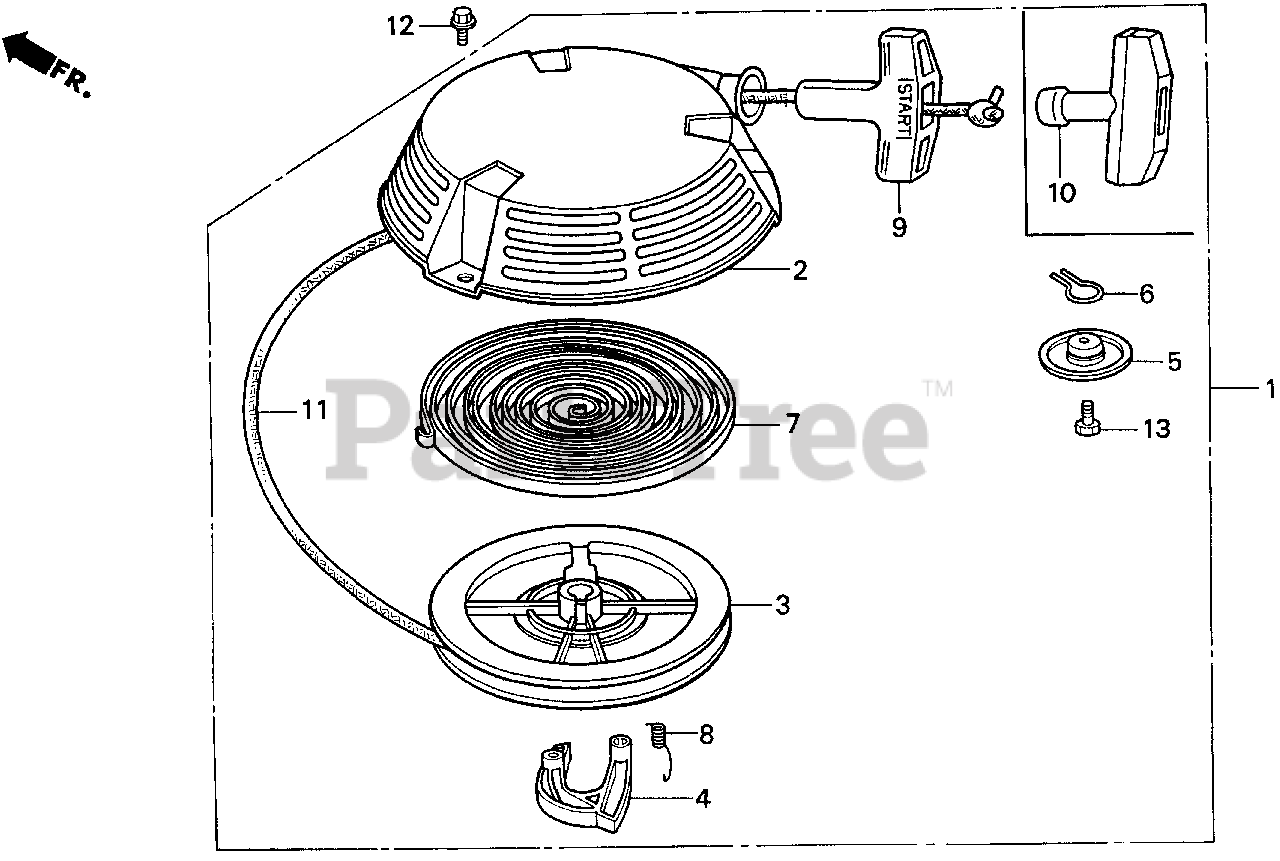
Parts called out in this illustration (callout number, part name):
1	STARTER ASSY., RECOIL *R8* (BRIGHT RED)
2	CASE, RECOIL STARTER *R8* (BRIGHT RED)
3	PULLEY, RECOIL STARTER
4	RATCHET, STARTER
5	PLATE, FRICTION
6	SPRING, FRICTION
7	SPRING, RETURN
8	SPRING, RETURN
9	KNOB, RECOIL STARTER
11	ROPE, RECOIL STARTER (#4X55")
11	ROPE (#4X55")
12	BOLT, FLANGE (6X8)
13	BOLT, HEX. (6X20)
